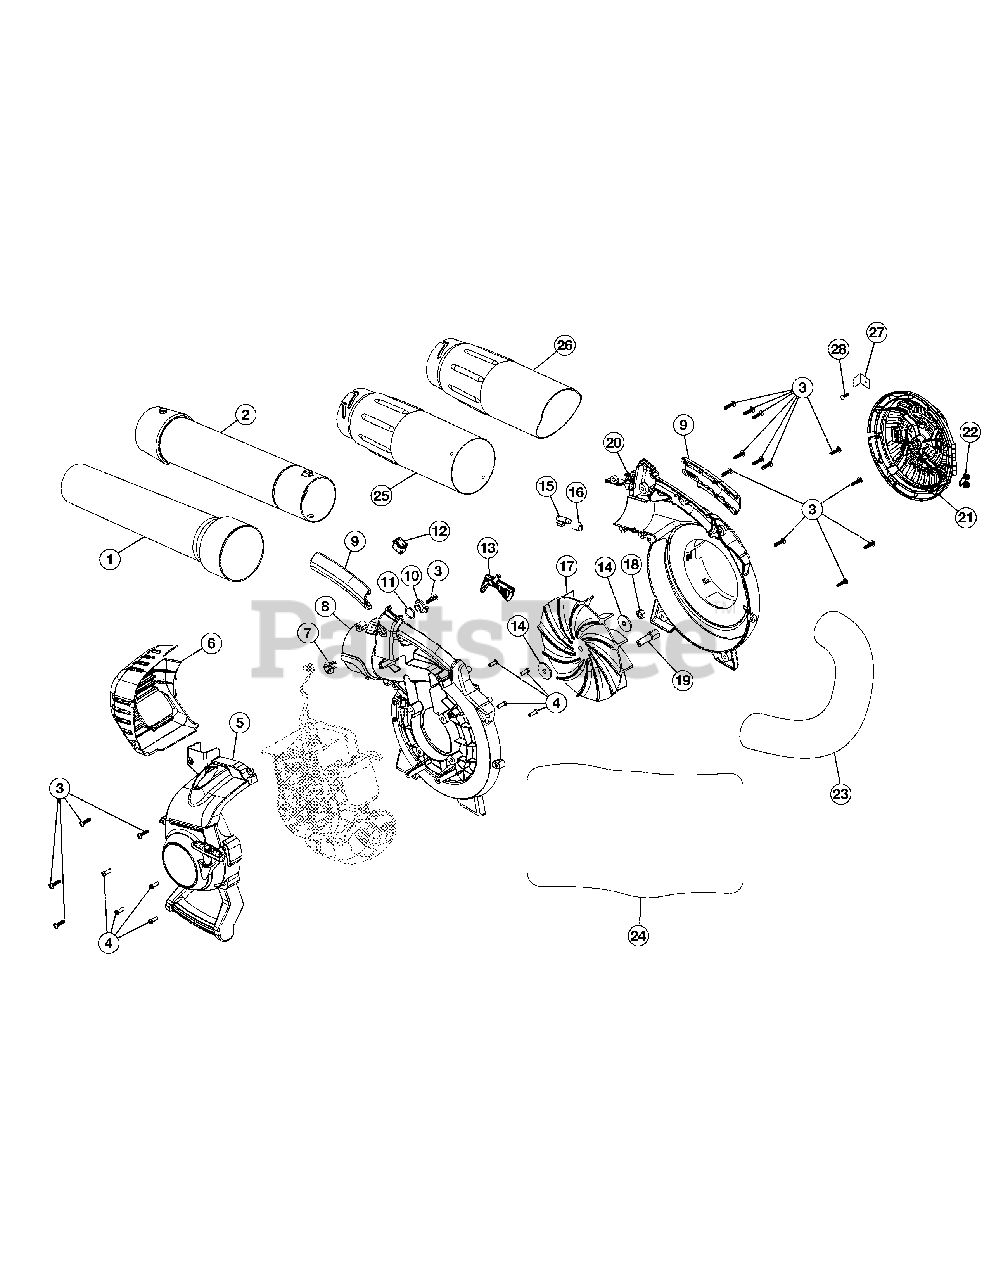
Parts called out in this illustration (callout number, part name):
1	Lower Tube
2	Upper Tube
4	Screw
5	Engine Cover Assembly (Incl. 3 & 4)
6	Muffler Cover Assembly (Incl. 3)
7	Outer Trigger Lock
8	Impeller Housing
9	Handle Grips
10	Inner Trigger Lock
11	Wavey Washer
13	Throttle Trigger
14	Washer
15	Latch Tube
16	Latch Spring
17	Impeller
18	Nut
19	Adapter
20	Impeller Housing
21	Intake Cover
22	Spring
25	Upper Vac Tube
26	Lower Vac Tube
27	Door Lock
28	Screw
